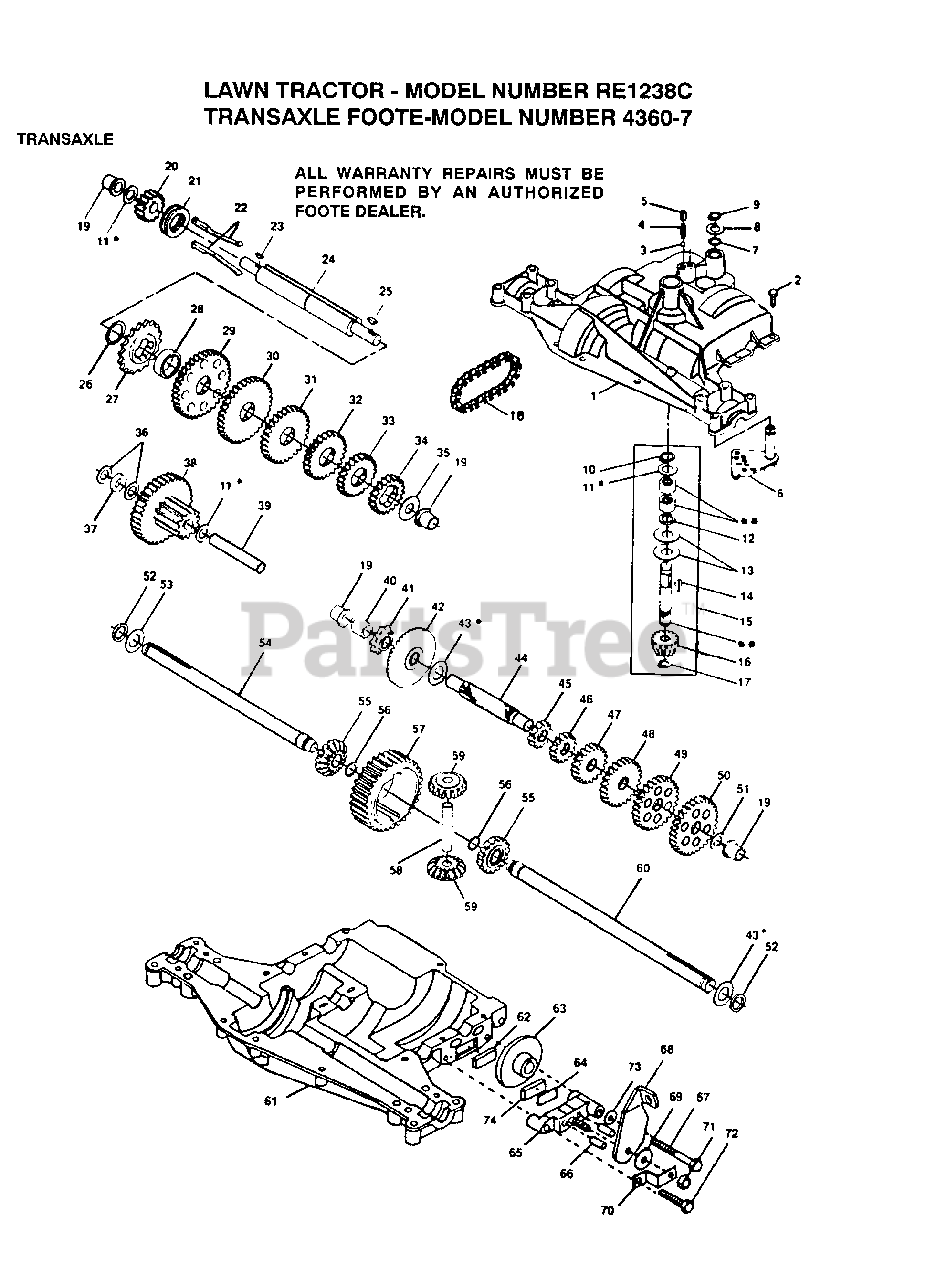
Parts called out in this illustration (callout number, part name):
1	HOUSING UPPER
3	BALL DETENT
4	SPRING, DETENT
5	SCREW, SET
6	ASSY SHIFTER
8	WASHER PLAIN
8A	WASHER PLAIN
8B	WASHER PLAIN
8C	WASHER PLAIN
8D	WASHER PLAIN
8E	WASHER PLAIN
8F	WASHER PLAIN
9	RING RETAINING
10	RING RETAINING
11	WASHER PLAIN
11A	WASHER PLAIN
11B	WASHER, PLAIN .632 X 1.00 X .026
11C	WASHER PLAIN
11D	WASHER PLAIN
11E	WASHER PLAIN
11F	WASHER PLAIN
11G	WASHER PLAIN
11H	WASHER, PLAIN .632 X 1.00 X .060
11I	WASHER PLAIN
13	WASHER, PLAIN .632 X 1.38 X .046
14	KEY WOODRUFF #9
15	ASSY KIT INPUT SHAFT
16	PINION, BEVEL, 14 TEETH
17	RING, RETAINING
18	CHAIN, 24 PITCHES
19	BEARING, FLANGE
20	GEAR SPUR, 14 TEETH
21	COLLAR CLUTCH
22	KEY CLUTCH
23	KEY WOODRUFF #3
24	SHAFT INTERMEDIATE
25	KEY, WOODRUFF, #61
26	RING, RETAINING
27	SPROCKET, 18 TEETH
29	GEAR, SPUR, 37 TEETH
30	GEAR, SPUR, 35 TEETH
31	GEAR, SPUR, 30 TEETH
32	GEAR, SPUR, 25 TEETH
33	GEAR, SPUR, 22 TEETH
35	WASHER, PLAIN .640 X 1.37 X .061
36	WASHER, PLAIN .632 X 1.00 X .026
37	SPACER .630 X 1.00 X .169
38	ASSY GEAR COMB 12&35 TEETH
39	SHAFT IDLER
40	SPACER .635 X .875 X .755
41	SPROCKET, 9 TEETH
42	GEAR, BEVEL, 42 TEETH
43	WASHER PLAIN
43A	WASHER PLAIN
43B	WASHER PLAIN
43C	WASHER PLAIN
43D	WASHER PLAIN
43E	WASHER PLAIN
43F	WASHER, PLAIN .758 X 1.25 X .031
43G	WASHER PLAIN
43H	WASHER PLAIN
43I	WASHER PLAIN
43J	WASHER PLAIN
43K	WASHER PLAIN
43L	WASHER PLAIN
44	SHAFT, DRIVE
45	GEAR, SPUR, 12 TEETH
46	GEAR SPUR, 15 TEETH
47	GEAR, SPUR, 20 TEETH
48	GEAR, SPUR, 25 TEETH
49	GEAR, SPUR, 28 TEETH
50	GEAR, SPUR, 31 TEETH
51	WASHER, PLAIN .632 X 1.00 X .060
53	WASHER PLAIN
54	AXLE LEFT HAND
55	GEAR, MITER, 15 TEETH
56	RING, RETAINING
57	GEAR, SPUR, 32 TEETH
58	SHAFT, CROSS
59	GEAR, MITER, 15 TEETH
60	AXLE, R.H.
61	HOUSING LOWER
62	PUCK, FRICTION
63	DISC, BRAKE
65	JAW, BRAKE
66	PIN, DOWEL
67	SCREW TAPPING
68	LEVER, ACTUATING
69	WASHER, PLAIN .321 X 1.00 X .055
70	BRACKET, ANTI-ROTATION
71	LOCKNUT 5/16-24
72	SCREW TAPPING
73	WASHER PLAIN
74	PUCK, FRICTION
